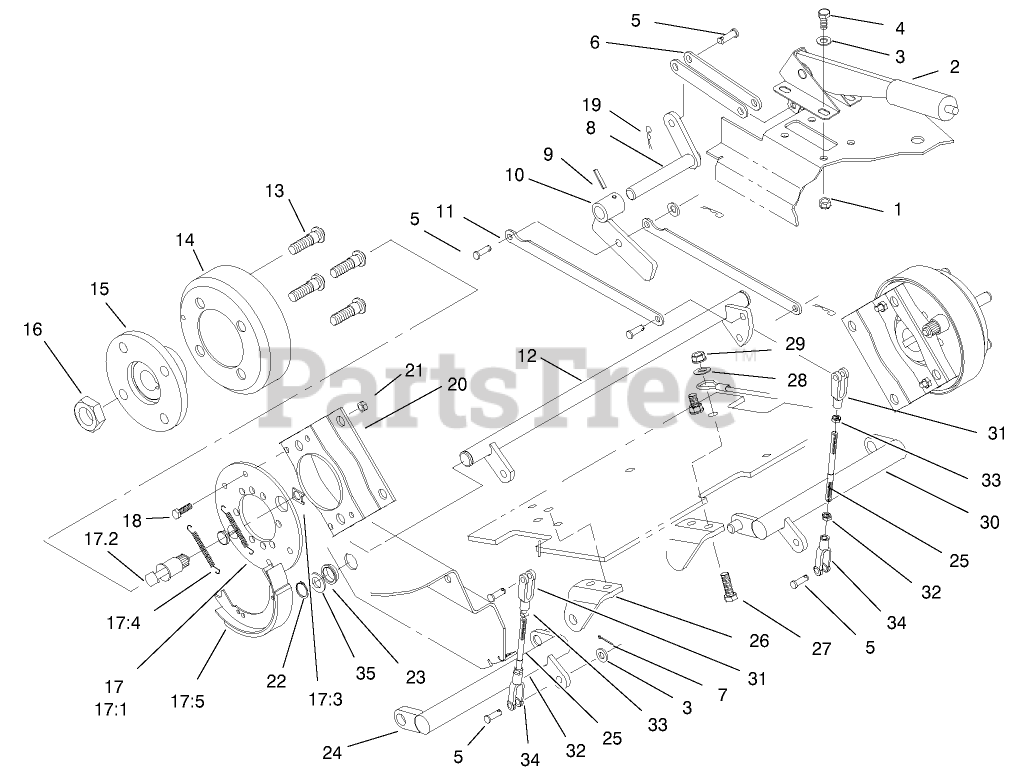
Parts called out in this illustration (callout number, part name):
1	NUT-LOCK, NI
2	LEVER-BRAKE
3	WASHER-PLAIN
4	SCREW-HH
5	PIN-CLEVIS
6	LINK-BRAKE
7	PIN-COTTER
8	TRANSFER SHAFT ASM
9	PIN-SPIRAL
10	BRAKE HUB ASM
11	LINK - CONNECT
12	TORSION SHAFT ASM
13	STUD-DRIVE
14	DRUM-BRAKE
15	Hub-Wheel
16	NUT-LOCK
17	BrakeASM
17:1	PLATE-BACKING
17:2	Cam Shaft
17:4	SPRING-RETURN
17:5	SHOE-BRAKE
18	SCREW-HH
19	PIN-COTTER
20	Bracket-Brake
21	NUT-LOCK, NI
22	Ring-Snap
23	BUSHING
24	RH BRAKE LEVER ASM
25	ROD-BRAKE
26	MOUNT-LEVER, BRAKE, RH
27	SCREW-HH
28	WASHER-FLAT
29	NUT-LOCK, NI
30	LH BRAKE LEVER ASM
31	YOKE
32	NUT-JAM
33	NUT-JAM
34	CLEVIS-ADJUSTABLE
35	Washer
